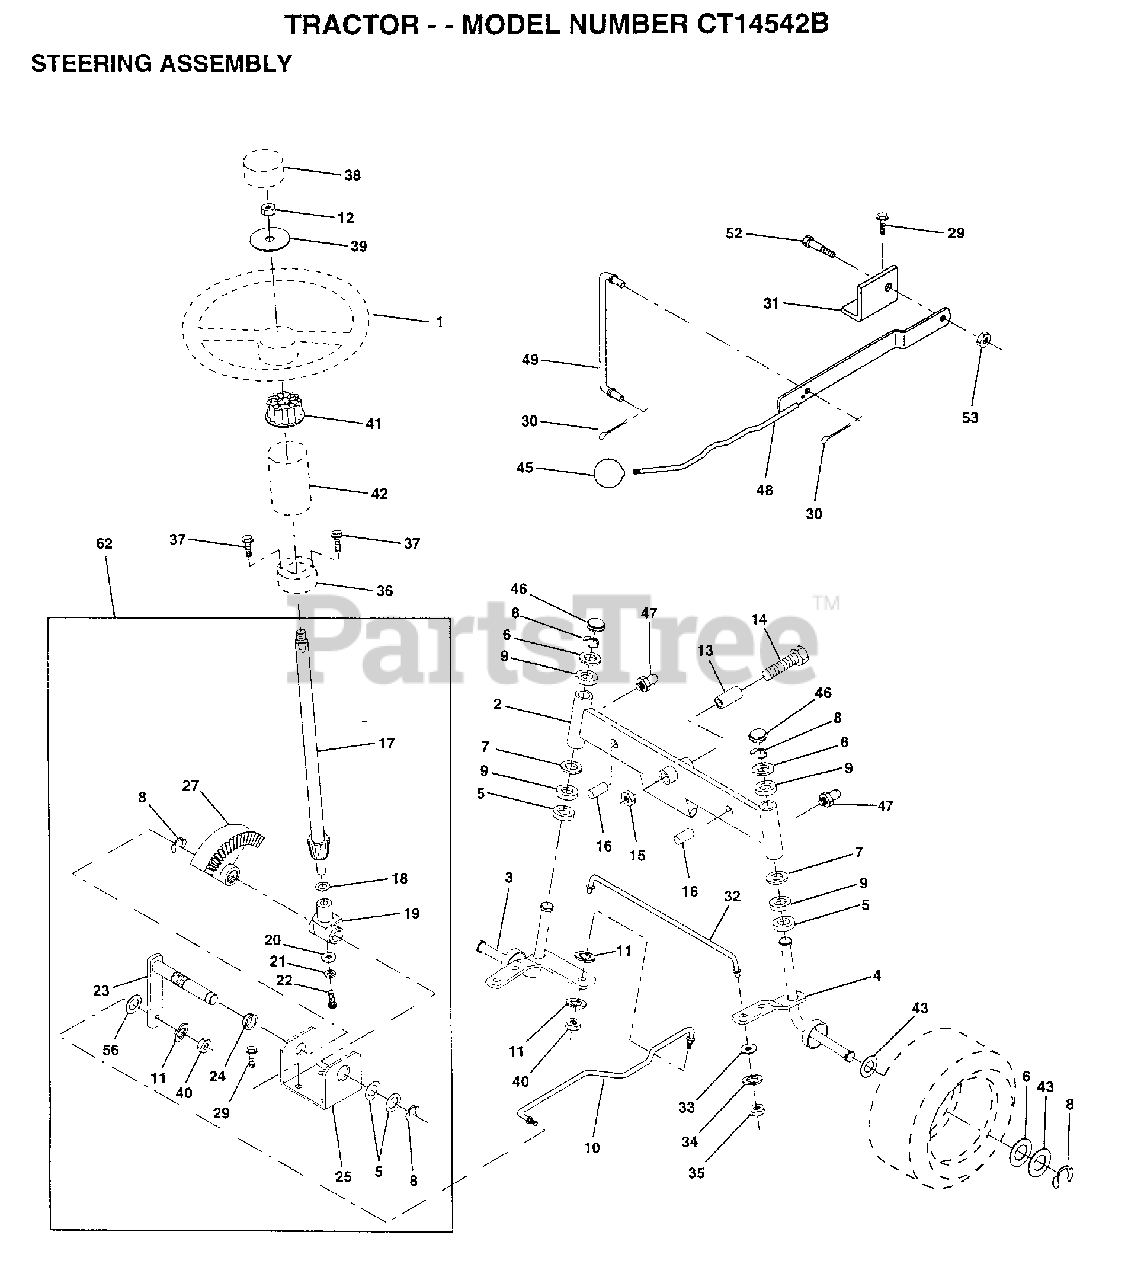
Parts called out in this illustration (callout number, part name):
1	WHEEL STR AYP BLK
2	AXLE ASM FRONT
3	SPINDLE LH
4	SPINDLE RH
5	WASHER .T
6	WASHER
7	WASHER
8	RING
9	COL. SRTG. BEAR.
11	LOCKWASHER
13	BEARING
14	BOLT HEX 5/8-11
15	"NUT-LOC,FLANGE LT"
16	AXLE PIN
17	STEERING SHAFT
18	THRUST WASHER
19	SUPPORT.SHAFT
21	LOCKWASHER
22	SCREW.SCKTHD.CAP
24	NYLINER T
25	"BRKT,STEERING"
27	GEAR SECTOR
29	SCREW
30	COTTER PIN
31	BRKT.PVT.MAN.LVR.
32	ROD.TIE.19.75
33	WASHER M
34	LOCKWASHER
35	NUT.LOCK.5/16-24
36	BUSHING.STRG.3/4
37	"SCREW-TT,10-32 FL"
38	CAP STEER AYP
39	WASHER
40	GRIPCO NUT
41	ADAPTER LT
42	BOOT SHAFT STEER
43	WASHER
45	CONTROL KNOB LT
46	CAP
47	ZERK M
48	LEVER.ASM.CLUTCH
49	LINK CLTCH W/NUTS
52	"BOLT, SHOULDER LT"
